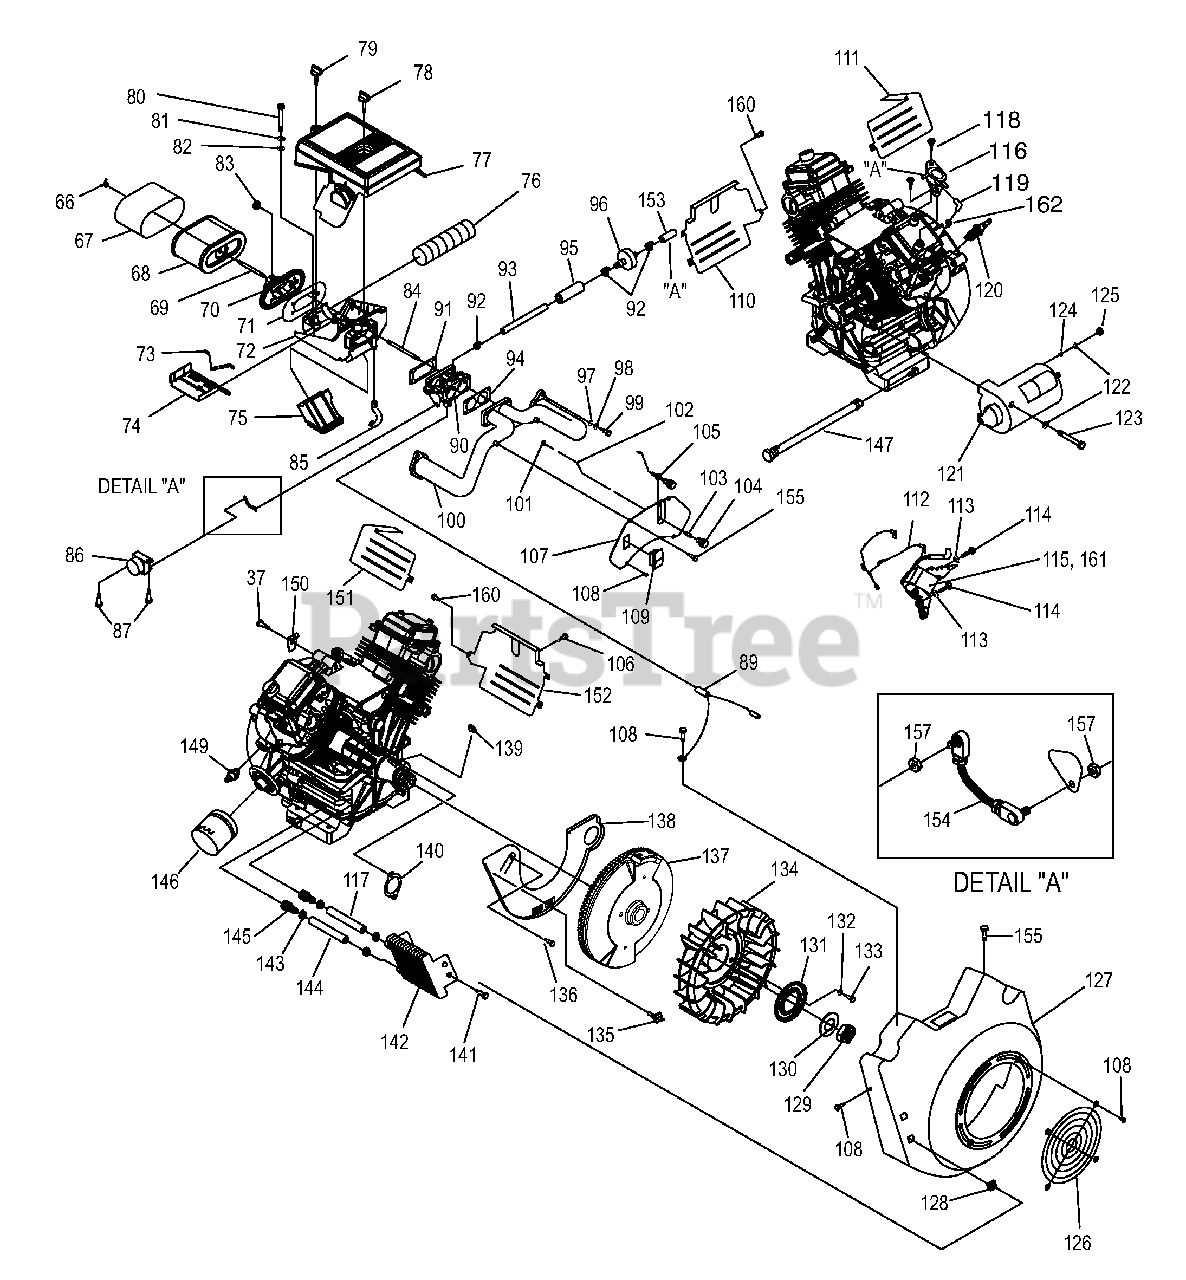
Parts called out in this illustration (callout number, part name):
66	WINGNUT, AIRBOX
67	PRECLEANER, AIR
68	ELEMENT, AIR CLEANER
69	STUD M6-1.0 X 73
70	ADAPTOR, SPIT BACK
71	GASKET, SPITBACK
72	BASE, AIRBOX
73	SPRING, WINTER/SUMMER VALVE
74	VALVE, SUMMER / WINTER
75	SNORKEL, AIR INTAKE
76	TUBE, HEAT RISER 50.8 I.D.
77	COVER, AIRBOX
78	KNOB, AIRBOX 17mm
79	KNOB, AIRBOX 95MM
80	SCREW HHC M6-1.0 X 35
81	WASHER LOCK M6-1/4
82	WASHER FLAT 1/4
83	NUT, HEX FLANGE WHIZ M6-1.0
84	STUD, METRIC
85	HOSE, BREATHER
86	CONTROLLER ASSEMBLY
87	SCREW HHTT M5-0.8 X 10
89	ASSEMBLY, WIRE
90	CARBURETOR (GT-990)
91	GASKET, CARB TO SPACER (GT-990)
92	CLAMP HOSE BAND 1/4
93	HOSE1/4 ID SAE 30R7 SETIFLEX II
94	GASKET, MANIFOLD TO CARBURETOR
95	SLEEVING, FLEXO HW 3/4 3"
96	FILTER, FUEL
97	WASHER FLAT M8
98	WASHER LOCK M8
99	SCREW SHC M8-1.25 X 30
100	MANIFOLD, INTAKE
101	NUT HEX M3-0.5
102	ROD, SUMMER / WINTER VALVE
103	BUSHING, MINI CONTROL PANEL
104	KNOB, CONTROL SUMMER / WINTER
105	CHOKE ASSEMBLY
106	SCREW TAPTITE M5-0.8 X 8 ZP
107	PANEL, CONTROL FACE PLATE
108	SCREW TAPTITE M6-1.0X 10 YELLOW CHROME
109	SWITCH ROCKER
110	WRAPPER, LOWER CYLINDER 2
111	WRAPPER, UPPER CYLINDER 2
112	ASSEMBLY, GROUND WIRE
113	WASHER LOCK M6-1/4
114	SCREW TAPTITE M6-1.0 X 25 BP
115	ASSY, IGN COIL W/DIODE NO ADV
116	PUMP, IMPULSE
117	HOSE, 3/8" ID x 6-1/2" SAE J30R9
118	SCREW, HHFCS M6-1.0 X 16 G8.8
119	ELBOW, RUBBER 90 DEG. GASOLINE
120	SPARKPLUG, CHAMPION RC14YC
121	STARTER, DELCO REMY SD80
122	WASHER LOCK M8-5/16
123	SCREW HHC M8-1.25 X 85 G8.8
124	WASHER, FLAT M8
125	NUT, HEX M8-1.25 YELLOW ZINC
126	GUARD,FAN
127	HOUSING, BLOWER GAS COOLER
128	NUT, GROMMET 1/4 PLUG
129	NUT,HEX M24
130	WASHER, M24
131	PLATE, FAN
132	WASHER SHAKEPROOF INT M8 SS
133	SCREW HHC M8-1.25 X 12 G8.8
134	FAN, NYLON
135	ASSY,GROUND WIRE CONNECTOR
136	SCREW TAPTITE M6-1X10 YELLOW CHROME
137	FLYWHEEL ASSEMBLY
138	PLATE, BACKING GT990 W/OIL COOL
139	KEY, WOODRFF 4 X 19D
140	GASKET, MANIFOLD / PORT
141	PLASTITE,1/4-15 X 3/4
142	COOLER, OIL
143	CLAMP, HOSE OETIKER 16.5mm
144	HOSE, 3/8" I.D. X 6" SAE J30R9
145	BARBED STR 1/4NPT X 3/8
146	OIL FILTER
147	ASSEMBLY, OIL DRAIN HOSE
149	SWITCH, OIL PRESS
150	BRACKET, AIRBOX SUPPORT
151	WRAPPER, UPPER CYLINDER 1
152	WRAPPER, LOWER CYLINDER 1
153	HOSE,1/4" SAE 30R7 SETIFLEX II
154	ASSY, ROD, GOV. STEPPER MOTOR
155	SCREW HHHC M6-1.0 X12
157	NUT, LOCK HEX M3-0.5 (GT-990)
160	SCREW HHFC M6-1.0 X 10mm
161	ASSY, IGN COIL W/DIODE NO ADV
162	CLAMP, HOSE BAND GREEN
